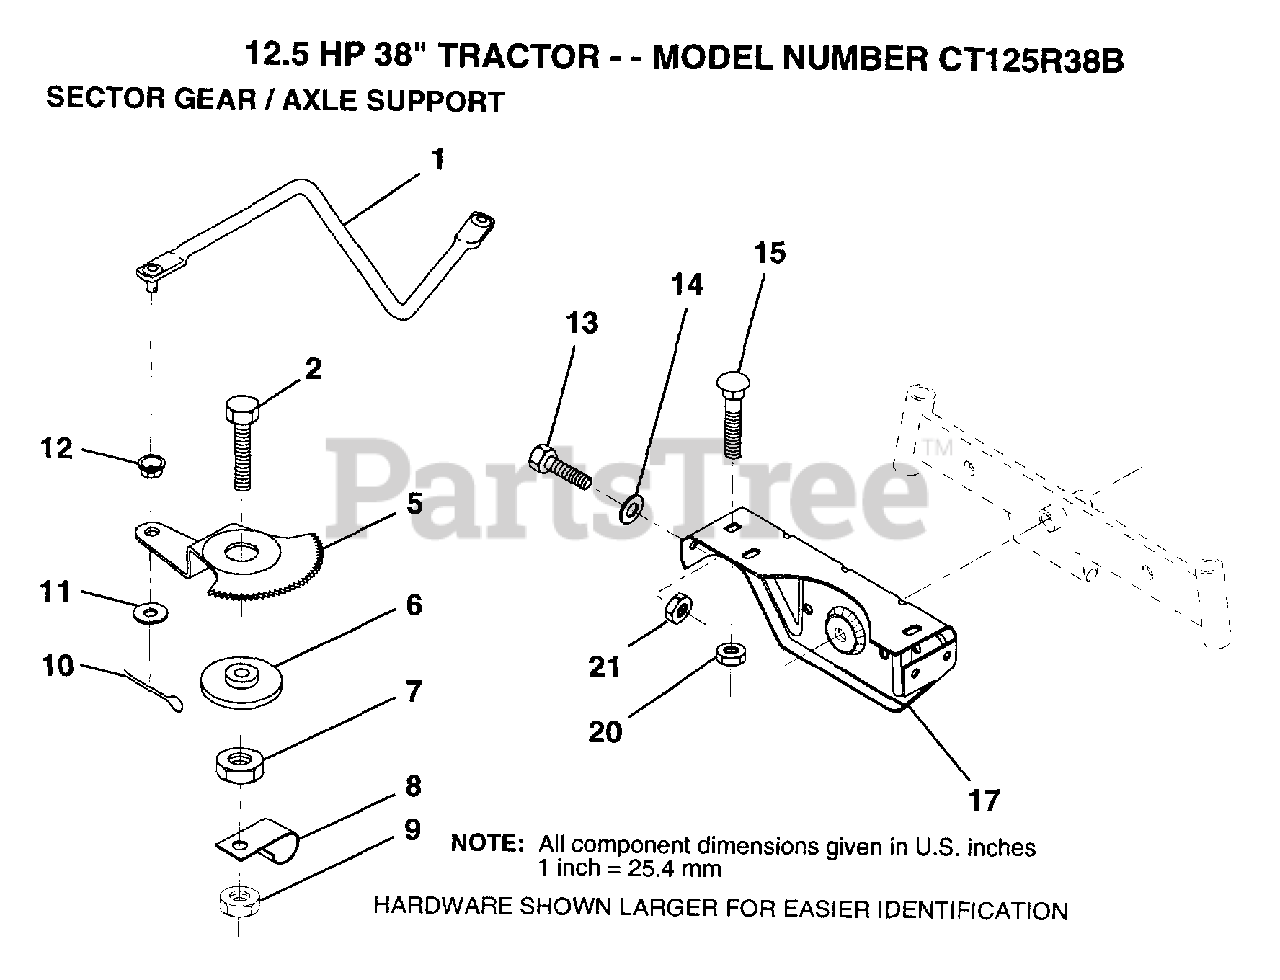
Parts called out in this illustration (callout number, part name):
1	DRAG LINK
2	"BOLT,HEX"
5	GEAR SECTOR
6	BUSHING
7	NUT
8	CLIP INSULATOR
9	NUT LTV
10	COTTER PIN
11	WASHER
12	BUSHING.DRAGLINK
13	BOLT
14	WASHER
15	BOLT
17	SUPT AXLE FRONT
